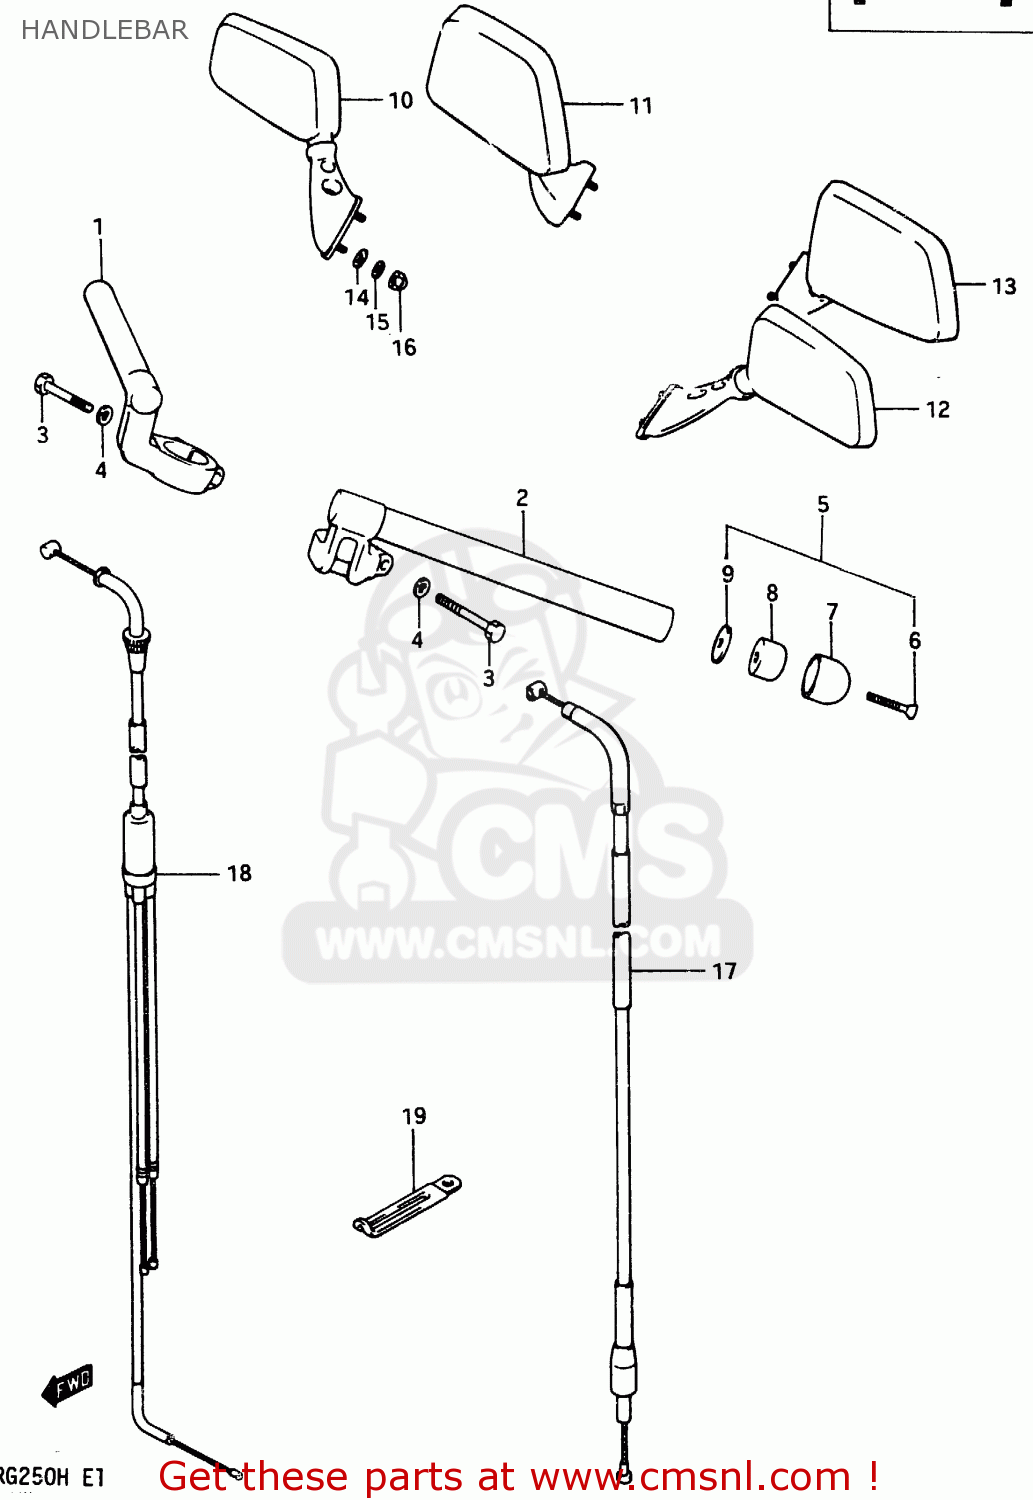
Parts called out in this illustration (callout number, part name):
1	HANDLEBAR, RH
2	HANDLEBAR, LH
3	BOLT 8X55
4	WASHER,LOCK,8.
5	BALANCER SET
6	SCREW
7	CAP,HANDLE BALANCER
8	BALANCER,HANDLEBAR
9	SPACER,BALANCER
10	MIRROR ASSY, REAR VIEW RH
11	MIRROR ASSY,RH
12	MIRROR ASSY L
13	MIRROR ASSY,LH
14	WASHER
15	WASHER,LOCK
16	NUT 6MM
17	CABLE ASSY,CLUTCH
18	CABLE ASSY, THROTTLE
19	CLAMP
